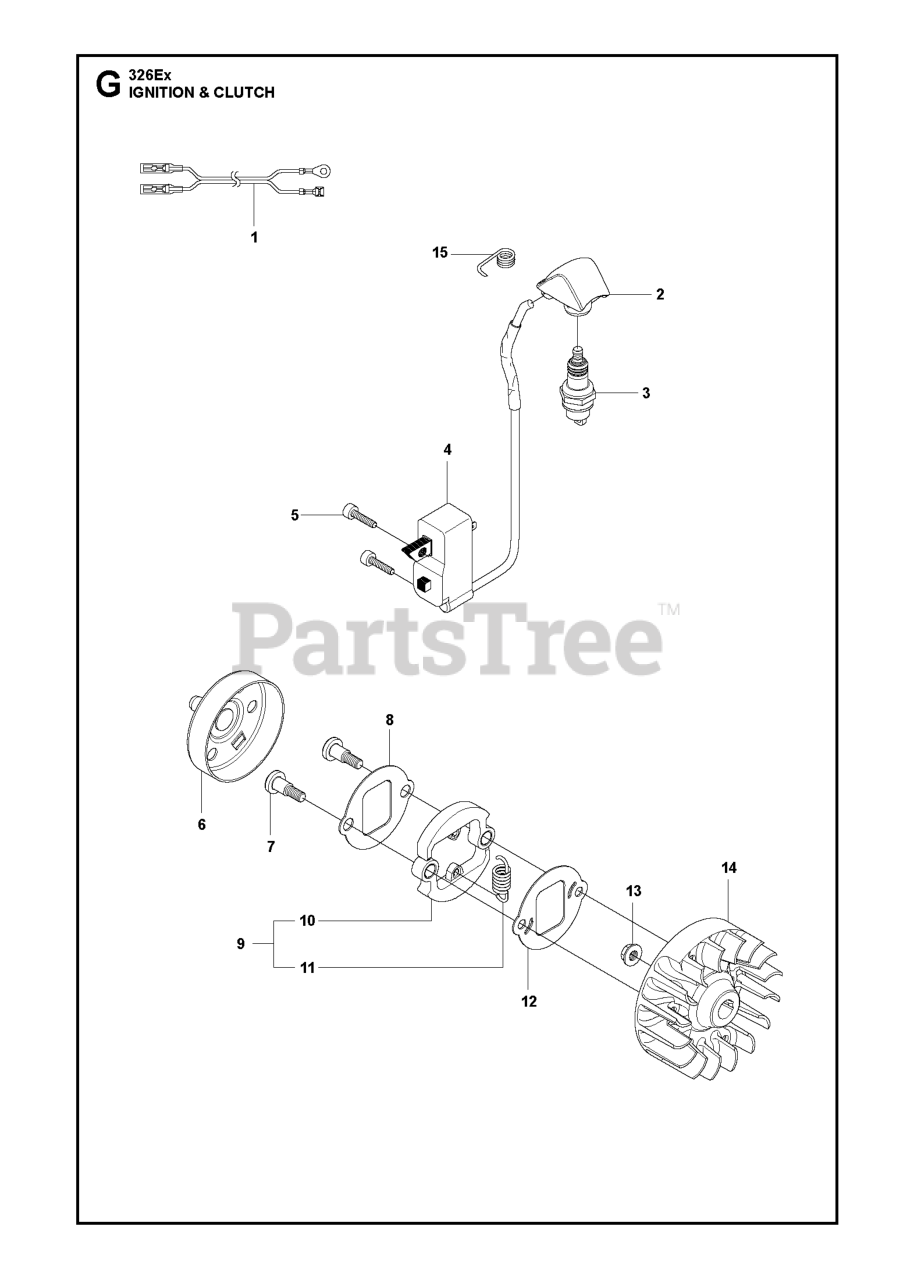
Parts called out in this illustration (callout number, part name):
1	SHORT CIRCUIT CABLE
2	SPARK PLUG CAP
3	SPARK PLUG RCJ6Y NLA
4	IGNITION MODULE OPS
6	CLUTCH DRUM
8	WASHER, CLUTCH
13	FLANGE NUT
15	SPRING
